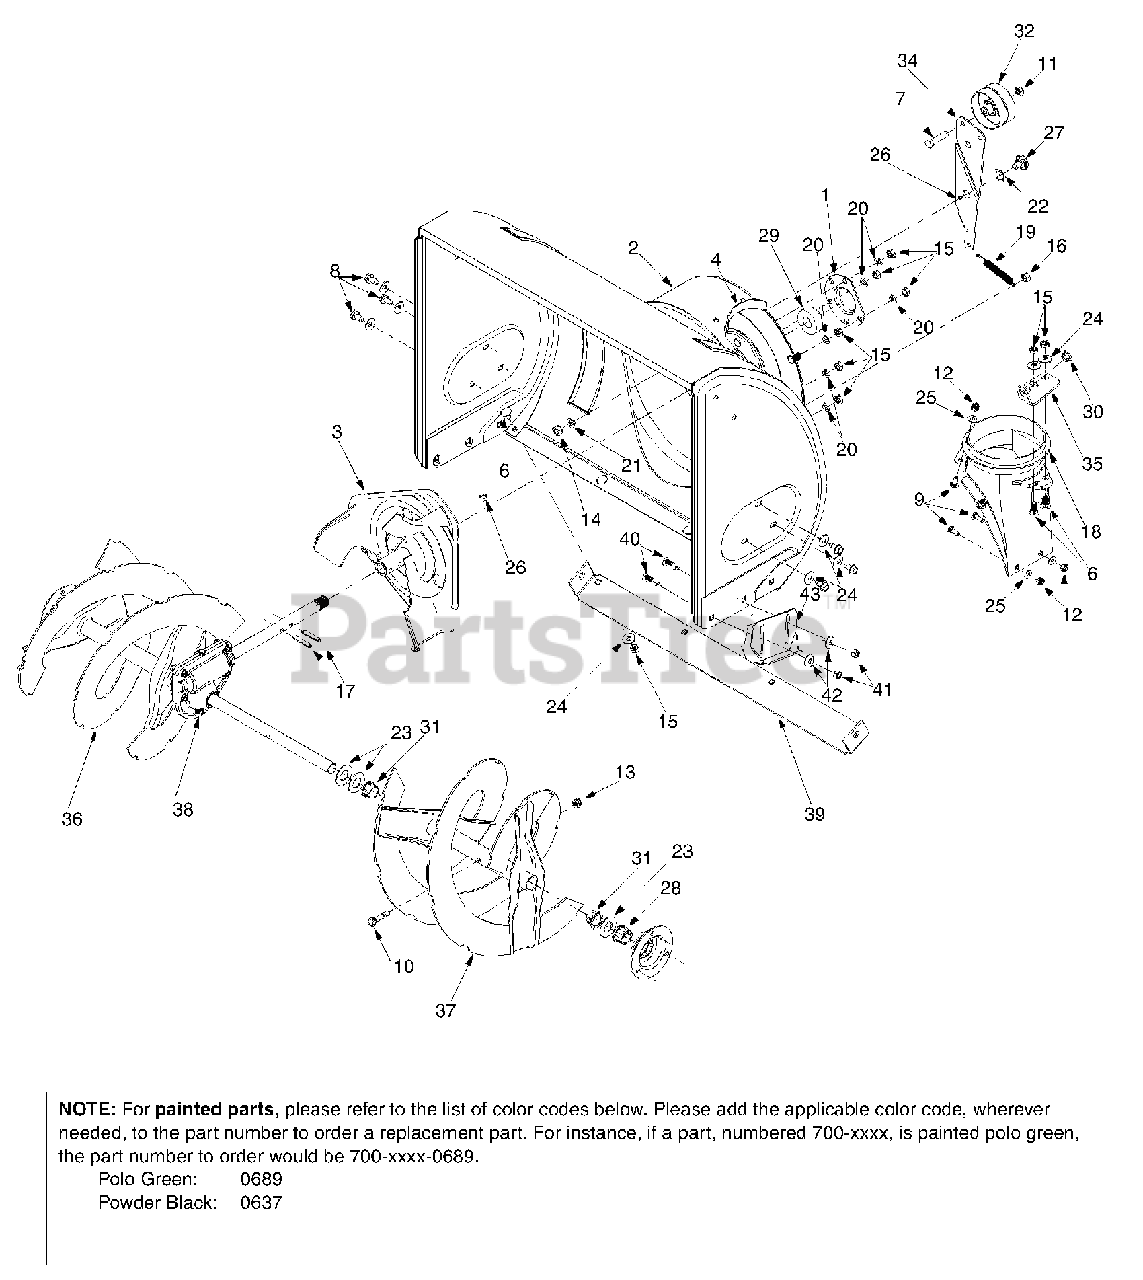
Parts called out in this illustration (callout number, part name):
1	Bearing Housing
6	Carriage Bolt 5/16-18 x .75" Gr.2
7	Hex Screw 3/8-24 x 1.5" Gr.5
8	Hex Washer Head Self-Tapping Screw 5/16-18 x .62"
9	Carriage Screw 1/4-20 x .75"
10	Shear Bolt 5/16-18 x 1.5"
11	Jam Nut 3/8-24
12	Hex Lock Nut 1/4-20
13	Hex Lock Nut 5/16-18
14	Hex Nut 3/8-16 Gr.2
15	Hex Nut 5/16-18 Gr.5
16	Hex Patch Nut 5/16-18
17	Spiral Pin
18	Chute Adapter
19	Extension Spring
20	Lock Washer
21	Lock Washer
22	Flat Washer
23	Flat Washer
24	Belleville Washer
25	Flat Washer
26	Grease
27	Shoulder Screw
28	Hex Flange Bearing
29	Flange Ball Bearing
30	Bushing
31	Flange Bushing
32	Flat Idler
38	Gear Assembly: Auger 28"
40	Carr. Bolt: 5/16-18 x 0.75
41	Hex Nut: 5/16-18 Gr.5
42	Belleville Washer
